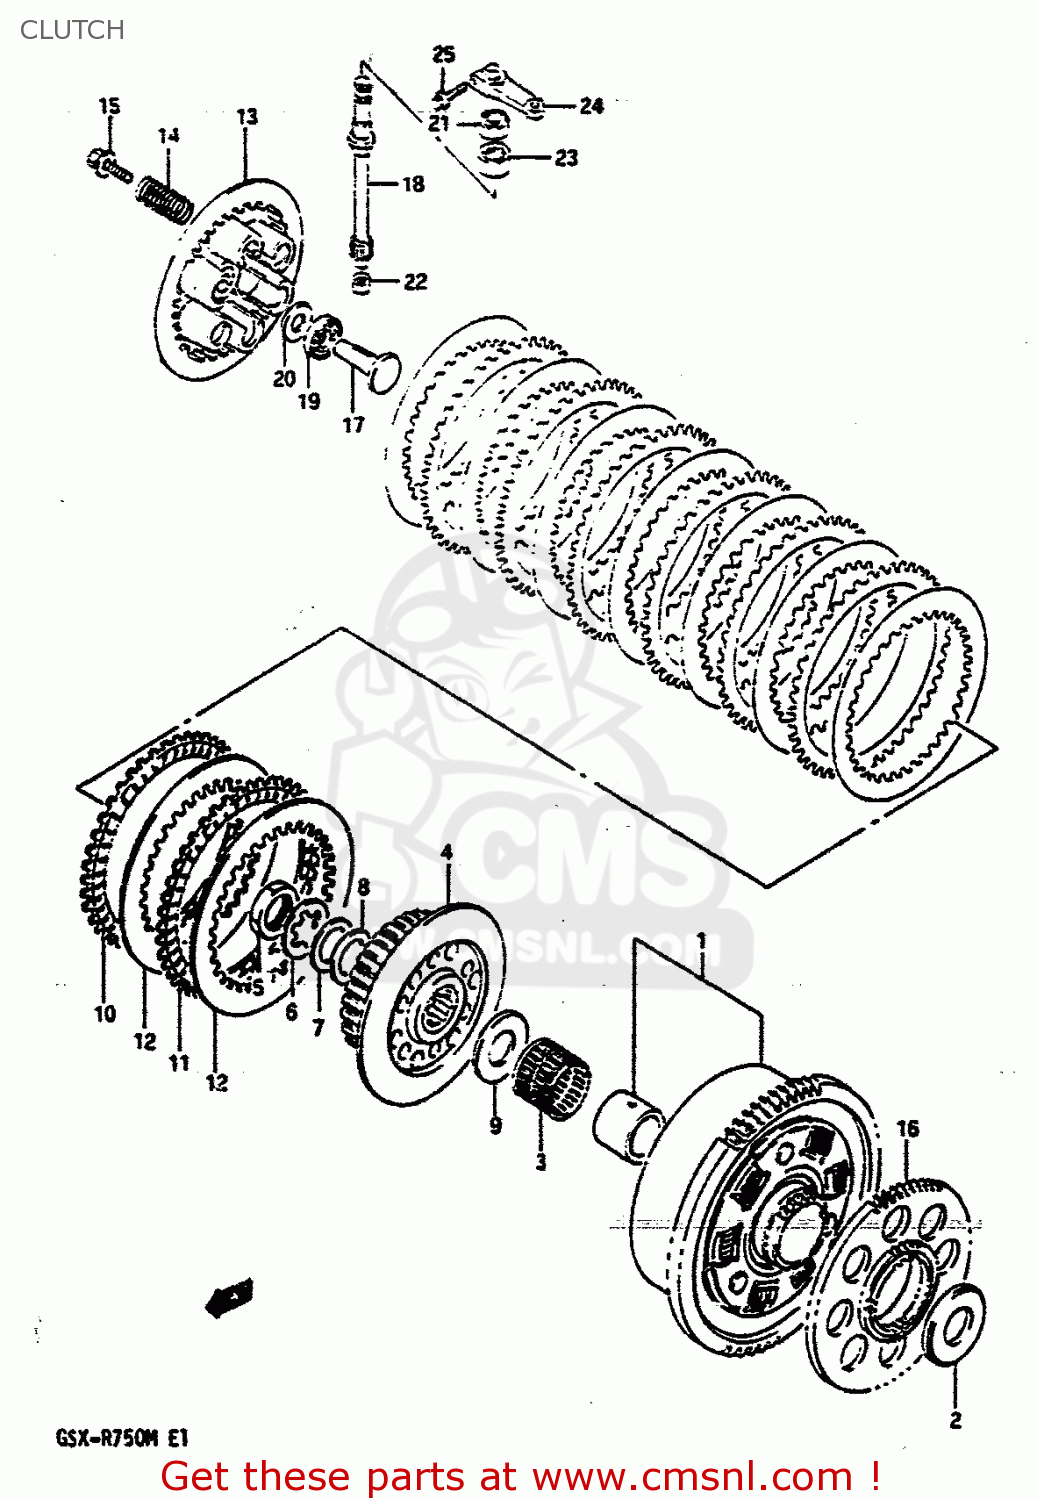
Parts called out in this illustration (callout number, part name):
1	GEAR ASSEMBLY,PRIMARY DRIVE
2	WASHER(25X54X2.5)
3	BEARING(35X40X35.8)
4	HUB,CLUTCH SLEEVE
5	NUT
6	WASHER,LOCK
7	WASHER
8	SHIM
9	WASHER(25X50X2.5)
10	PLATE,CLUTCH DRIVE (NAS)
11	PLATE,CLUTCH DRIVE NO.2 (NAS)
12	PLATE,CLUTCH DRIVEN (NAS)
13	DISC,CLUTCH PRESSURE
14	SPRING
15	BOLT(6X25)
16	GEAR,GENERATOR DRIVE
17	RACK,CLUTCH RELEASE
18	PINION,CLUTCH RELEASE
19	BEARING(15X28X2)
20	WASHER
21	OIL SEAL
22	BEARING 10X14X10
23	BEARING(15X22X12)
24	ARM,CLUTCH RELEASE
25	BOLT
